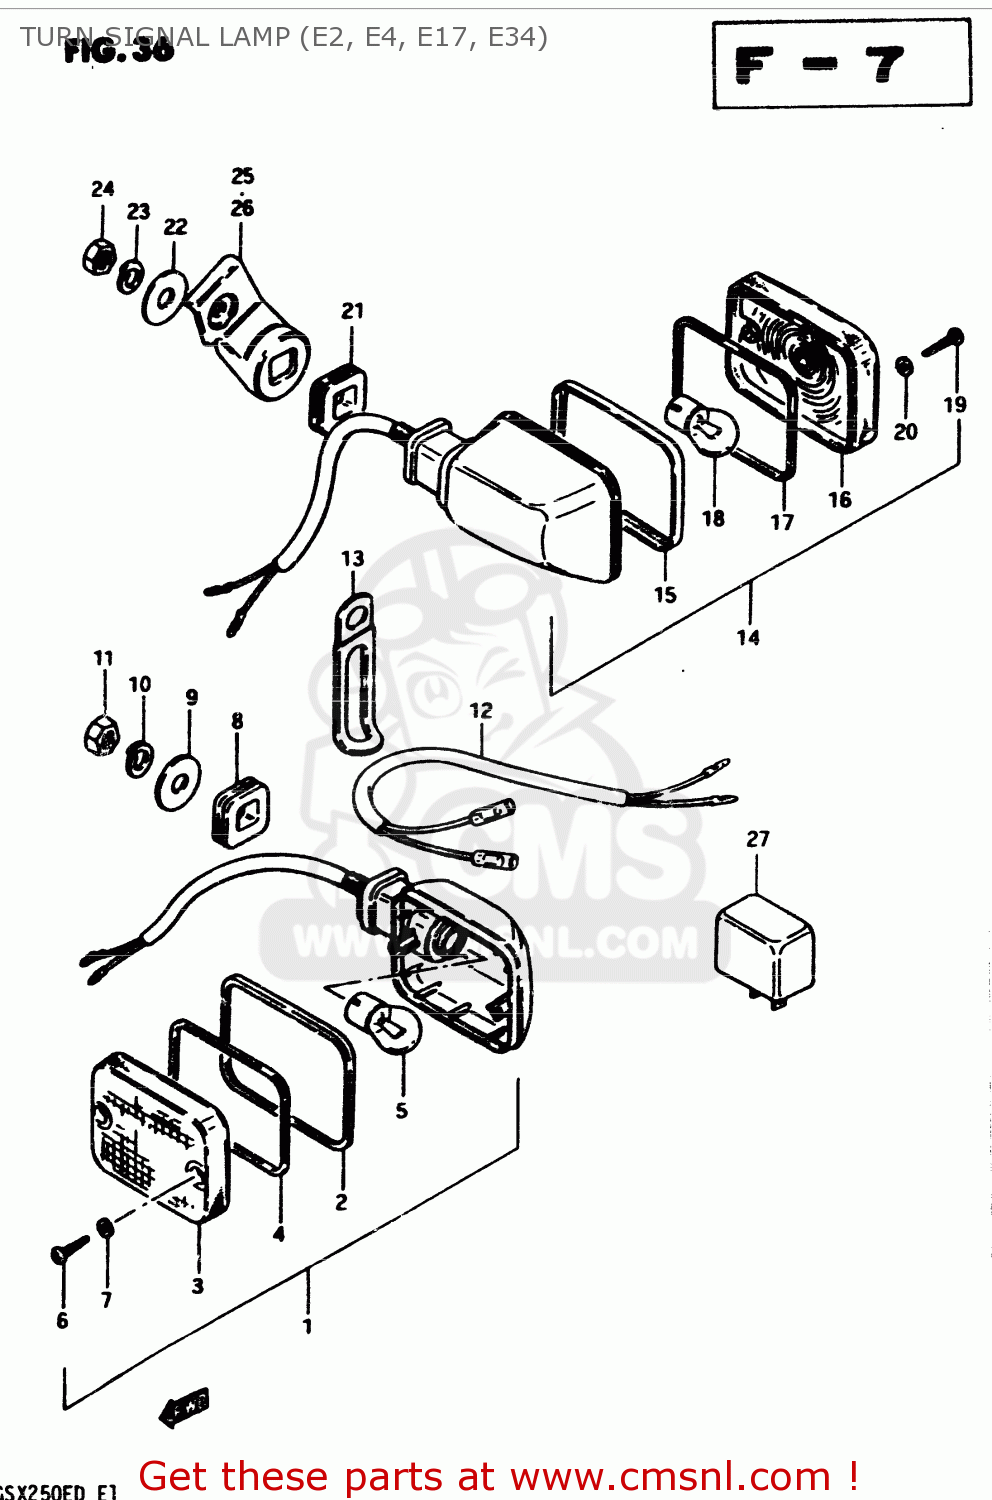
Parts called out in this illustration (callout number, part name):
1	LAMP ASSY,FR T
2	RIM
3	LENS
4	GASKET (NAS)
5	BULB(12V21W)
6	SCREW
7	GASKET (NAS)
8	CUSHION
9	WASHER (10.5X30X2.3)
10	LOCK WASHER
11	NUT
12	LEAD WIRE, TURN SIGNAL LAMP
13	CLAMP
14	LAMP, REAR TURN SIGNAL
15	RIM
16	LENS
17	GASKET (NAS)
18	BULB(12V21W)
19	SCREW
20	GASKET (NAS)
21	CUSHION
22	WASHER (10.5X30X2.3)
23	LOCK WASHER
24	NUT
25	BRACKET,REAR TURN SIGNAL
26	BRACKET,REAR TURN SIGNAL
27	RELAY,TURN SIGNAL
